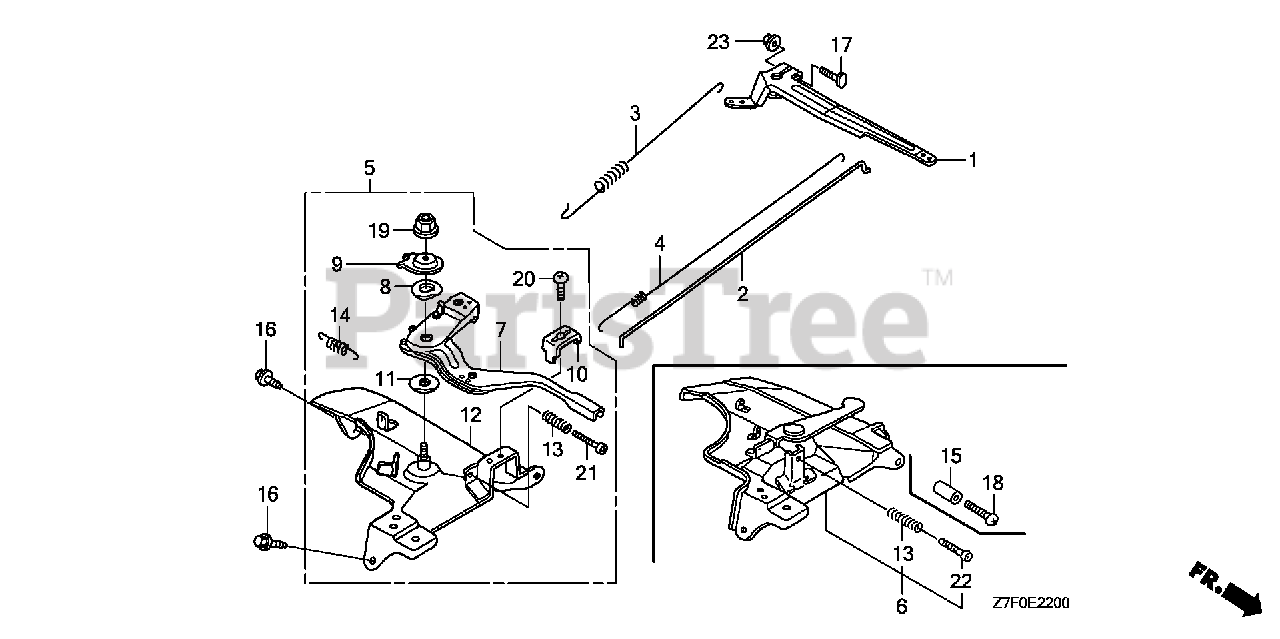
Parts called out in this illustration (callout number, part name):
1	ARM, GOVERNOR
2	ROD, GOVERNOR
3	SPRING, GOVERNOR (L=132.0MM)
4	SPRING, THROTTLE RETURN
6	CONTROL ASSY.
13	SPRING, CONTROL ADJUSTING
15	COLLAR, STOPPER
16	BOLT, FLANGE (6X12) (CT200)
17	BOLT, GOVERNOR ARM
18	SCREW, RECESSED (5X25)
22	SCREW, PAN (5X45)
23	NUT, FLANGE (6MM)
